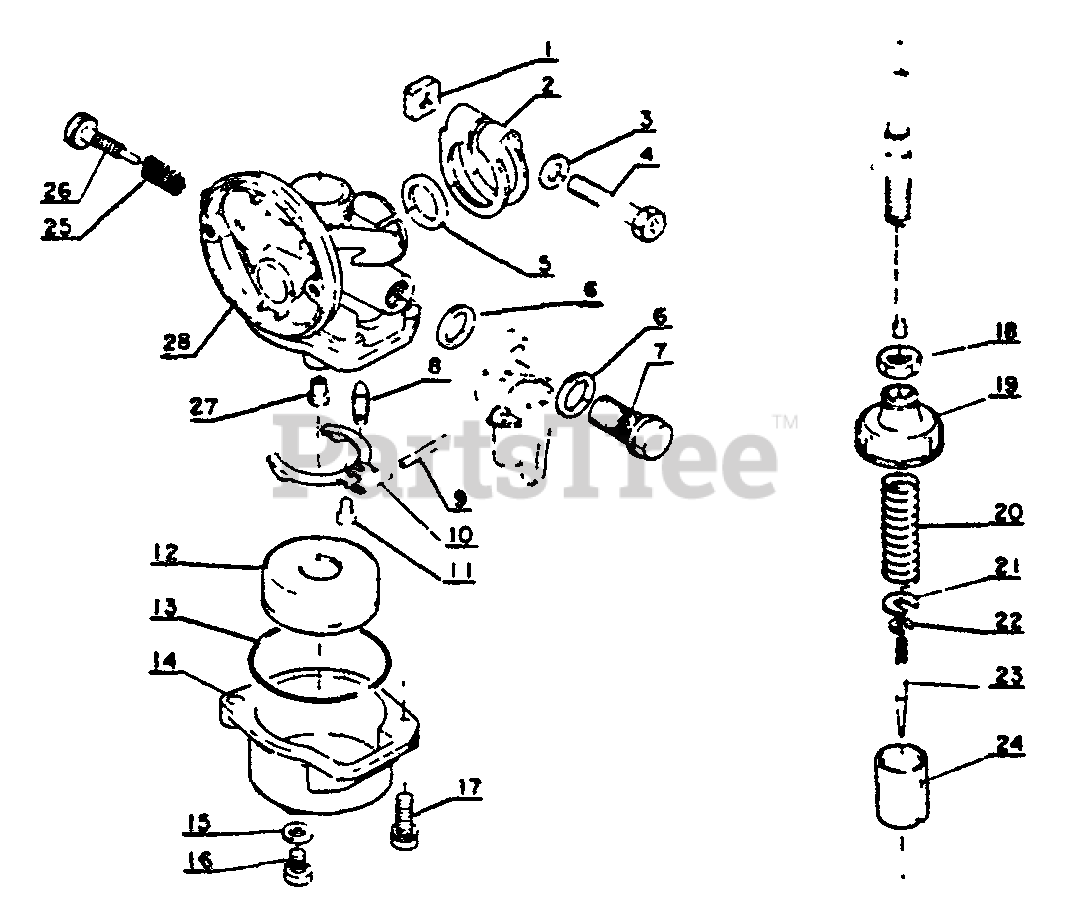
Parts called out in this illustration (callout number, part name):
1	NUT
2	CLAMP
3	WASHER - 5
4	BOLT
6	GASKET
7	BOLT, BANJO
8	VALVE, INLET NEEDLE
9	PIN, METERING LEVER
10	LEVER, METERING
11	SCREW - 4X6
12	FLOAT
13	O-RING
14	CHAMBER, FLOAT
15	GASKET, DRAIN
16	SCREW - 4X6
17	SCREW - 4X12
18	NUT
19	COVER - TOP
20	SPRING, THROTTLE
21	SEAT, SPRING
22	RING, RETAINING
23	NEEDLE, JET
24	VALVE, THROTTLE
25	SPRING, IDLE ADJUST
26	SCREW, IDLE ADJUST
27	VALVE, MIXTURE
28	BODY, CARBURETOR
